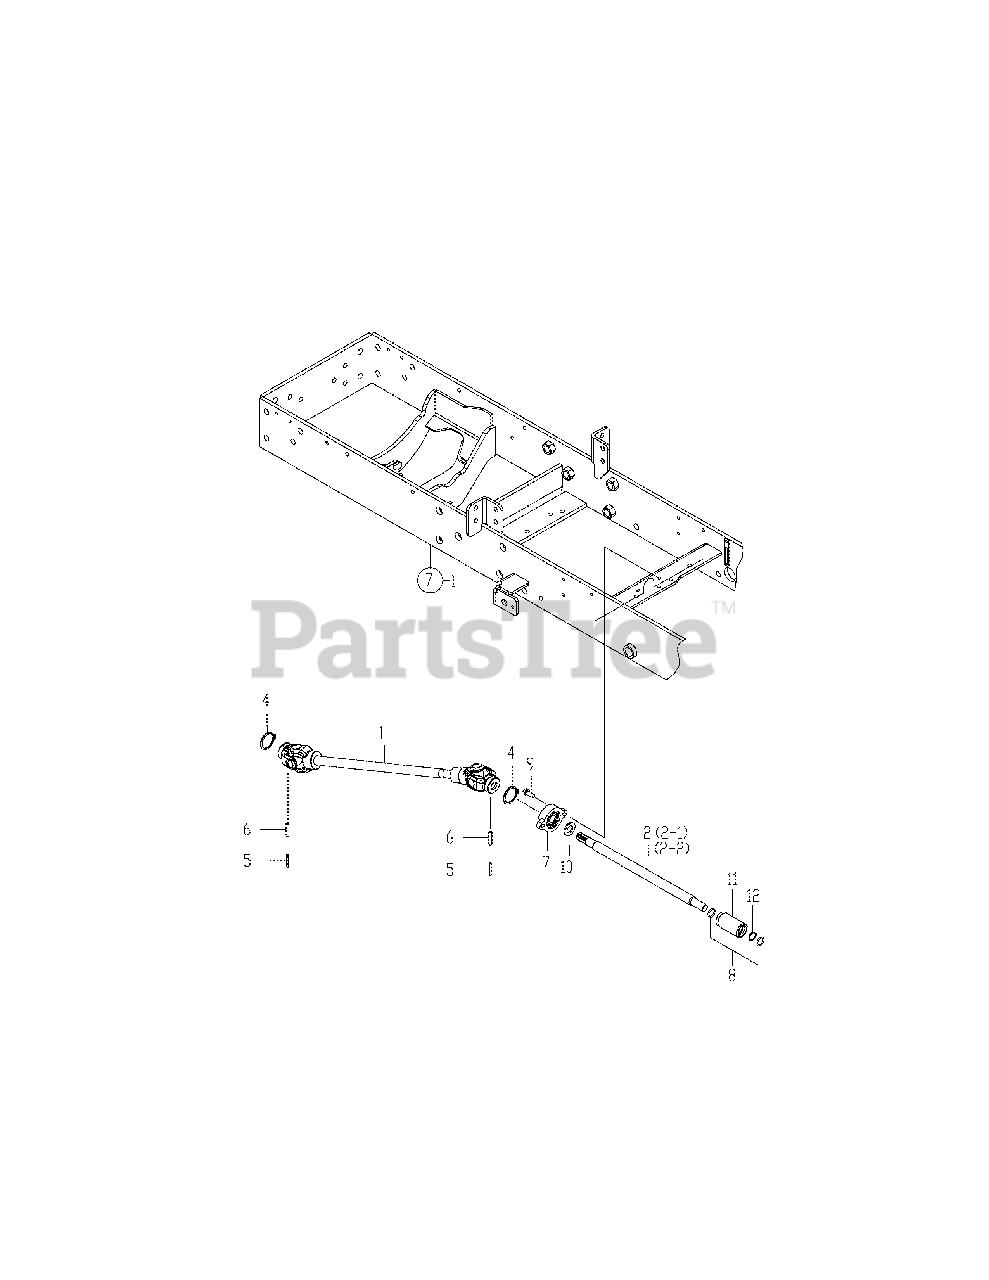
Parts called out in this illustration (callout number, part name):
1	Shaft Cmp,Pop. F
2	Shaft Assy, R
2-2	Shaft R, Propeller
5	Pin, 3.5A X 32
6	Pin, 6.0A X 32
8	Packing, P 16.0
10	Washer, 16
11	Collar, Spline
12	Circlip 15
